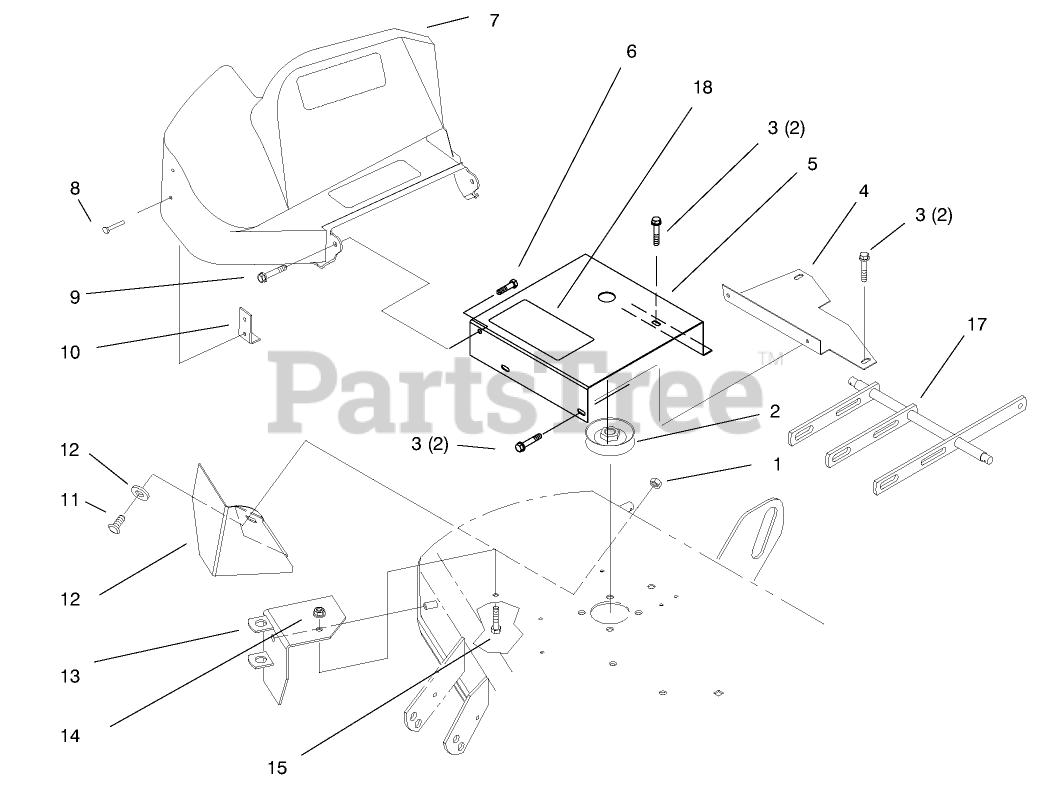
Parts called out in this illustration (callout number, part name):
1	NUT-LOCK, NI
2	PULLEY
3	SCREW-HWH
5	SHIELD / DECAL ASM
6	SCREW-HH
7	SHIELD-BELT
8	RIVET-POP
9	NUT-LOCK, NI
10	BRACKET-SUPPORT, SHIELD
11	SCREW-HH
14	NUT-HF
15	SCREW-HH
16	WASHER-FLAT
18	DECAL-DANGER
